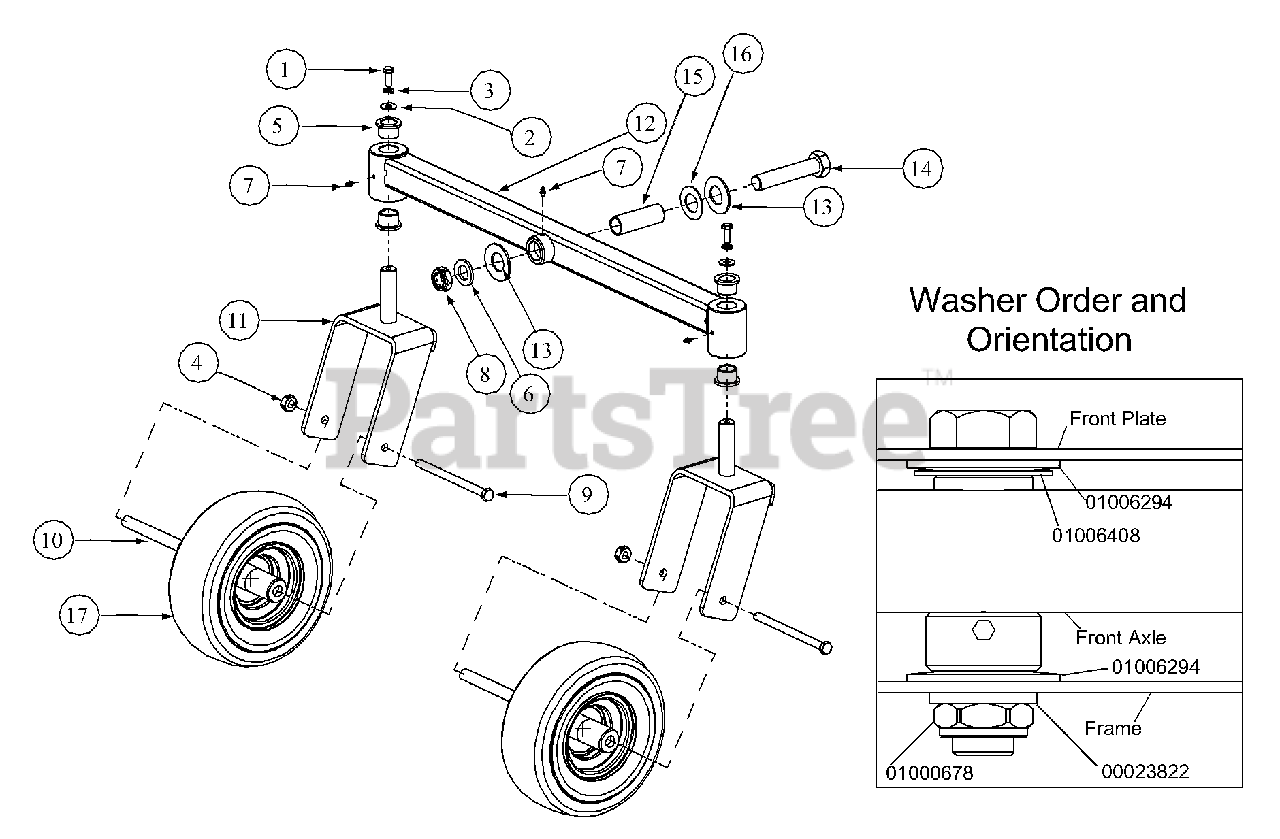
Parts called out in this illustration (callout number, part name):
1	Hex Cap Screw, 3/8-16, x 1
2	Flat Washer, .411 x 1.25 x 1.00
3	Lock Washer, 3/8
4	Center Lock Nut, 1/2-20
5	Flange Bearing, 1.013
6	Special Washer
7	Grease Fitting, 1/4-28 x 3/16
8	Jam Lock Nut, 1.0-14
9	Hex Cap Screw, 1/2-20 x 7.00
10	Spacer, .51 ID x .75 OD x 5.83 Lg
11	Caster Wheel Bracket Assembly
12	Narrow Front Axle Assembly
13	Belle Washer, 1.25 ID x 2.500 OD x .1
14	Hex Cap Screw, 1-14 x 5.0
15	Spacer, 1.005 ID x 1.25 OD x 3.6
16	Flat Washer, 1.25 ID x 2.25 ODx .075
17	Wheel Assembly, 11 x 4-5.00
